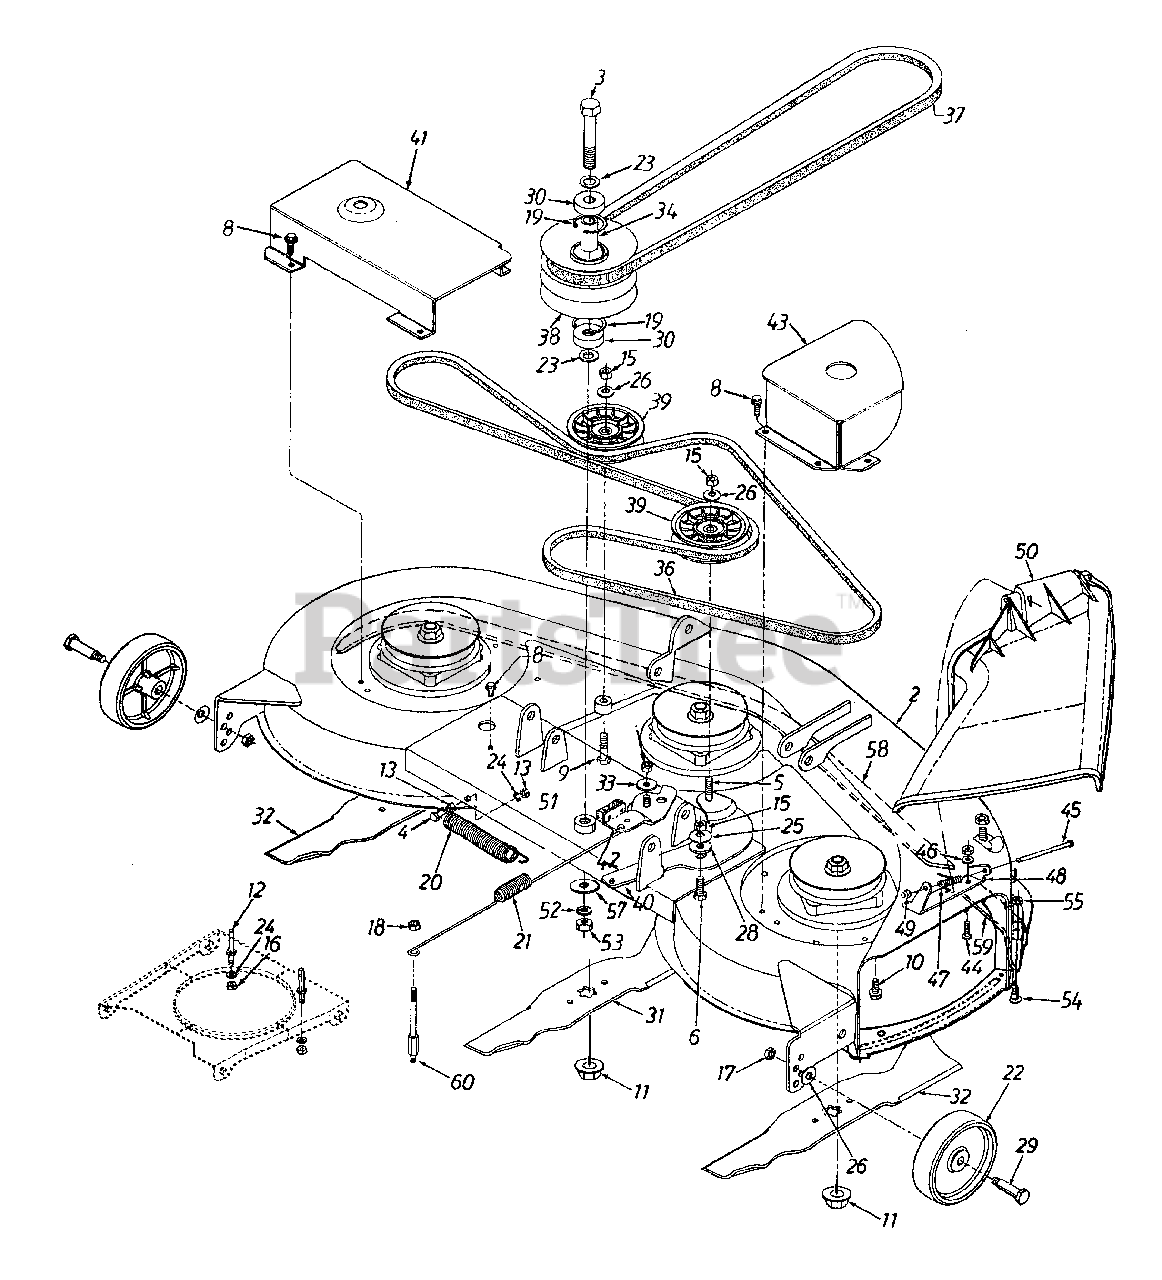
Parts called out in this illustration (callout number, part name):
4	Hex Bolt 1/4-28 x 1.25" Lg.
5	Hex Bolt 3/8-24 x 1.5" Lg.
6	Hex Bolt 3/8-24 x 1" Lg.
8	Hex Wash. Hd. TT-Tap Scr.
9	Hex Bolt 3/8-24 x 2" Lg.
10	Hex Flange Bolt 5/16-24 x .75"
11	Hex Flange L-Nut 5/8-18 Thd.
12	Belt Guard Pin
13	Hex Nut 1/4-28 Thd.
15	Hex Nut 3/8-24 Thd.
16	Hex Nut 1/4-20 Thd. (Gr. 5)
17	Hex Top Jam Nut 3/8-16 Thd.
18	Hex Center L-Nut 5/16-18 Thd.
19	Int. Snap Ring
20	Ext. Spring .88" O.D. x 6.17"
21	Ext. Spring .788" O.D. x 15.5"
22	Deck Wheel
23	Fl-Wash. .635" I.D. x 1" O.D.
24	L-Wash. 1/4" I.D.
25	Bell-Wash. 3/8" x 1.125" x .062"
26	Bell-Wash. 3/8" x .87" x .064"
28	Shoulder Spacer .625" I.D.
29	Shld. Bolt .498" x 1.525"
30	Ball Brg. .625" I.D. x 1.574" O.D.
31	Blade 14.88" Lg.
32	Blade 16.28" Lg.
33	Shoulder Spacer
34	Spacer .635" I.D. x .088" O.D.
36	V-Belt
37	V-Belt
38	Pulley Double Deck 5" O.D.
39	Flat Idler Pulley 3.5 O.D.
44	Hex Bolt 1/4-20 x .62" Lg.
45	Hinge Pin
46	Bell-Wash. 1/4" I.D.
47	Torsion Spring
48	Hinge Mtg. Brkt.
49	Push Nut
50	Chute Ass'y. Comp.
51	Spacer .635" I.D. x 1" O.D.
52	L-Wash. 5/8" I.D.
53	Hex Nut 5/8-18 Thd.
54	Carriage Bolt 1/4-20 x .5" Lg.
55	Hex Sems Nut 1/4-20 Thd.
57	Fl-Wash. .635" I.D.
60	Return Spring Stud
